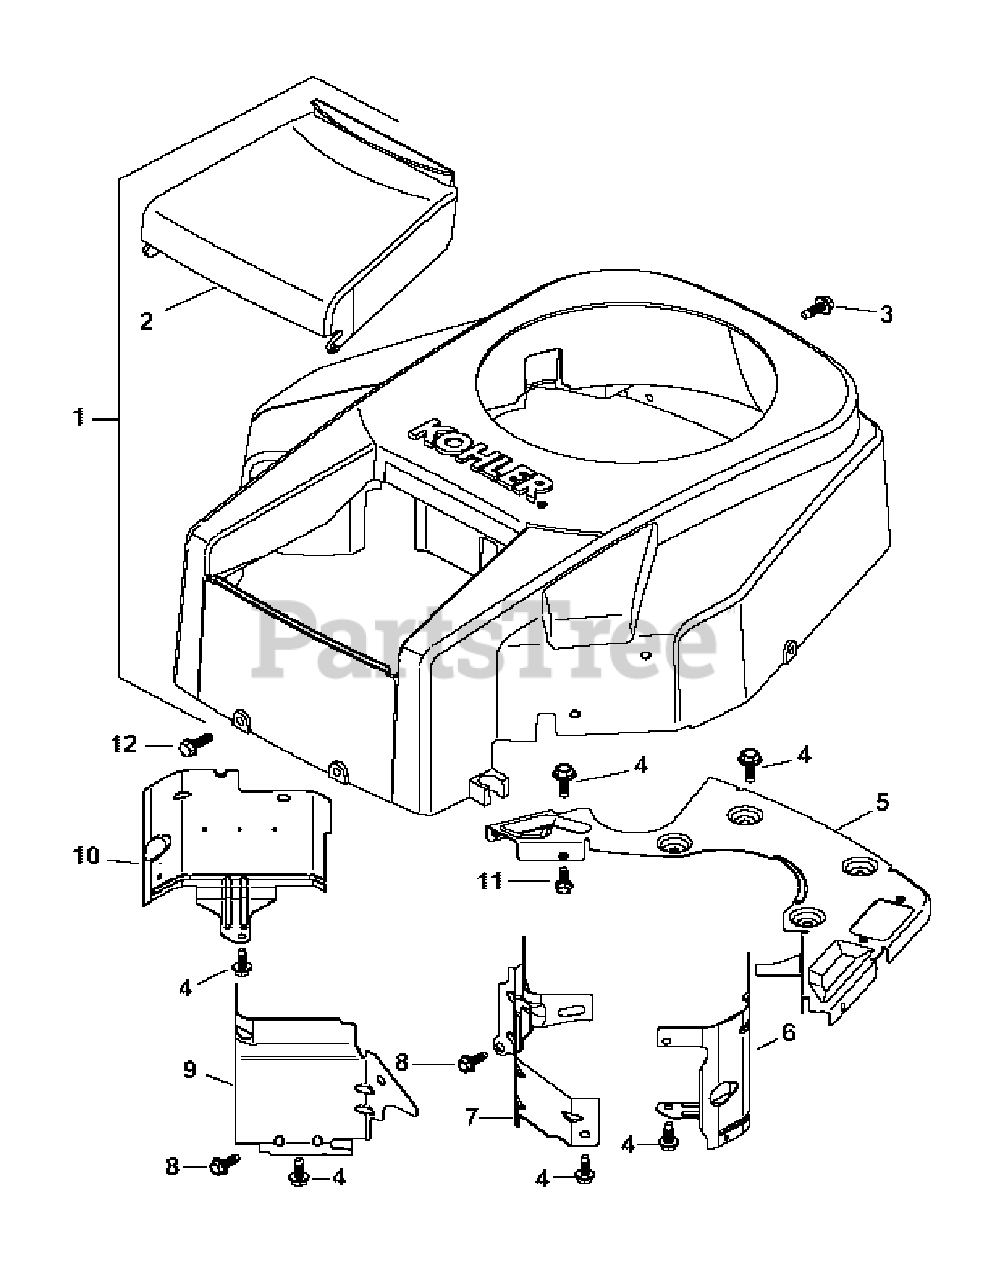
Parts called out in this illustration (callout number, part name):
1	Blower Housing
2	Air Cleaner Cover
3	Hex Flange Screw
4	Hex Flange Screw
5	Backing Plate (Regulator Opening)
6	Cylinder Barrel Baffle # 2
7	Valley Baffle # 2
8	Hex Flange Screw
9	Valley Baffle # 1
10	Cylinder Barrel Baffle # 1
11	Hex Flange Screw
12	Hex Cap Screw
